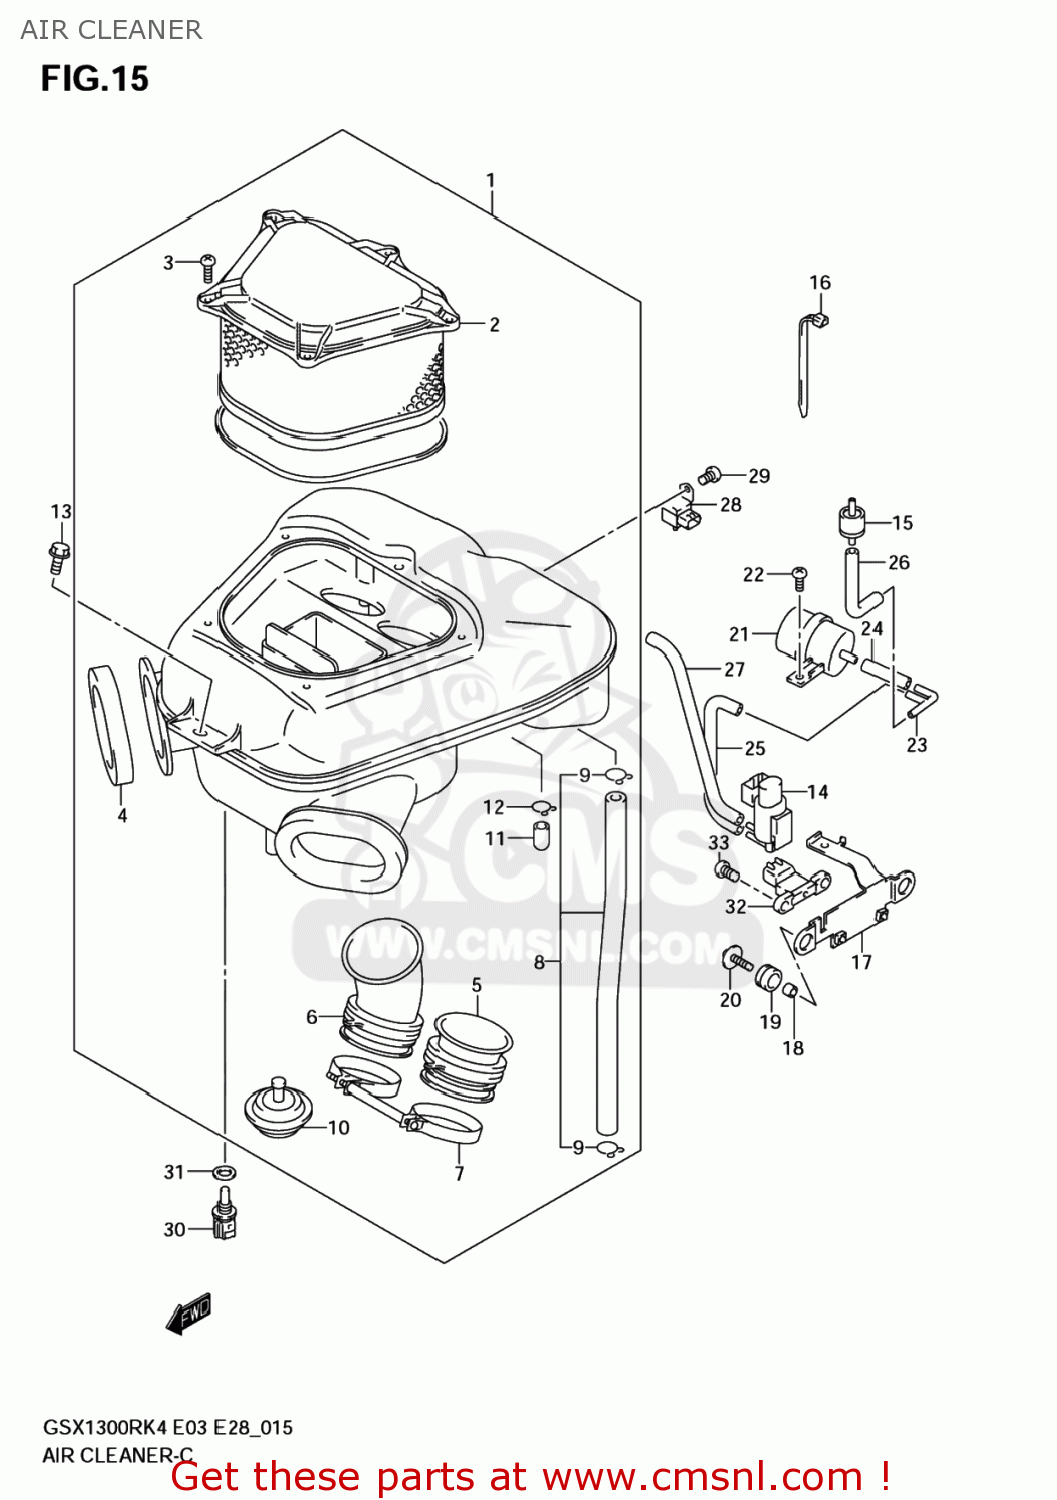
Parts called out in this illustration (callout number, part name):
1	CLEANER ASSY, AIR
2	FILTER ASSY,AIR CLEANER
3	SCREW,AIR CLEANER
4	CUSHION,DUCT
5	TUBE,OUTLET
6	TUBE,OUTLET
7	CLAMP
8	TUBE,BREATHER
9	CLIP
10	DIAPHRAGM,CONTROL VALVE
11	PLUG
12	CLIP
13	BOLT(6X16)
14	VALVE ASSY,3WAY SOLENOID
15	VALVE,CHECK
16	CLAMP(L:95)
17	BRACKET,SOLENOID VALVE
18	SPACER(6.5X9X6.5)
19	CUSHION
20	BOLT(6X20)
21	CHAMBER,VACUUM
22	SCREW 5X12
23	JOINT
24	HOSE(4X8X600)
25	HOSE(4X8X600)
26	HOSE(4X8X600)
27	HOSE(4X8X600)
28	SENSOR,BOOST
29	SCREW 6X10
30	SENSOR,WATER TEMP
31	GASKET(12X17X1) (NAS)
32	SENSOR,MAP
33	SCREW 6X12
